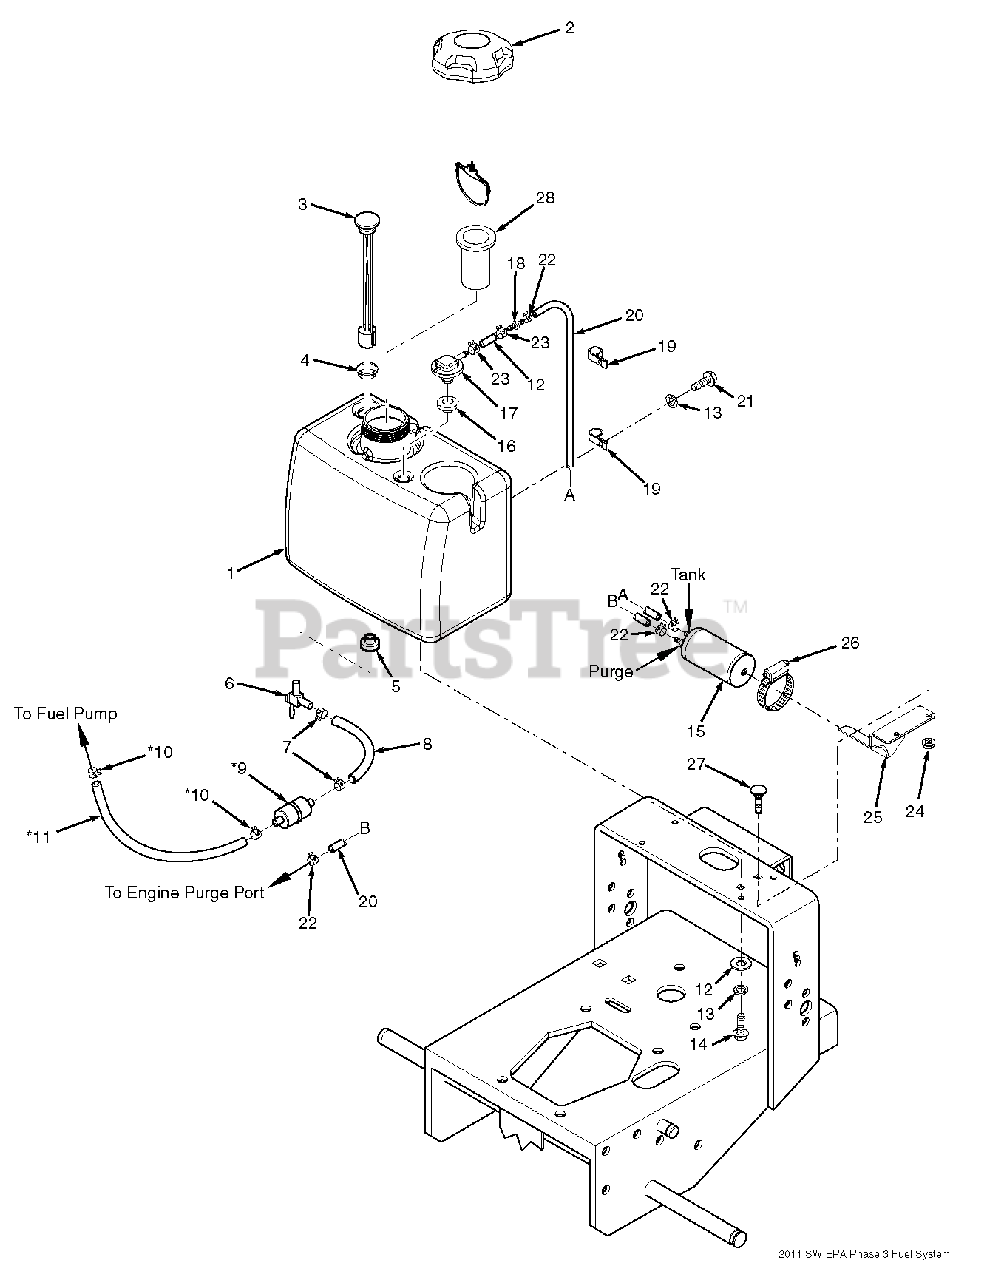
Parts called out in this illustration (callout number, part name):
1	Fuel Tank Assembly
2	Fuel Cap w/ Tether (E.P.A.)
3	Fuel Gauge Assembly
4	Seal, Fuel Gauge
5	Bushing, .56 Dia. Viton
6	Ball Valve w/Screen
7	Clamp, Fuel Hose
8	Fuel Hose, 1/4" ID
9	Fuel Filter
10	Clamp, Fuel Hose
11	Fuel Hose
12	Hose, Vapor Recovery 1/4"
13	Lockwasher, 5/16" Spring
14	Bolt, Hex Head 5/16-18 x 1"
15	Carbon Canister
16	Grommet, Viton,
17	Fitting, Remote Vent
18	Mender, 1/4 x 3/16 w/.02 Hole
19	Clamp, 3/8"
20	Hose, Vapor Recovery 3/16"
21	Bolt, Hex Head 5/16-18 x 3/4"
22	Clamp, Vapor Recovery Hose 3/16"
23	Clamp, Fuel Hose 7/32" ID
24	Nut, Serrated Flange 5/16-18
25	Bracket, Canister Mounting
27	Bolt, Carriage 5/16-18 X 1"
28	Tube, Fuel Tank Insert - 4"
